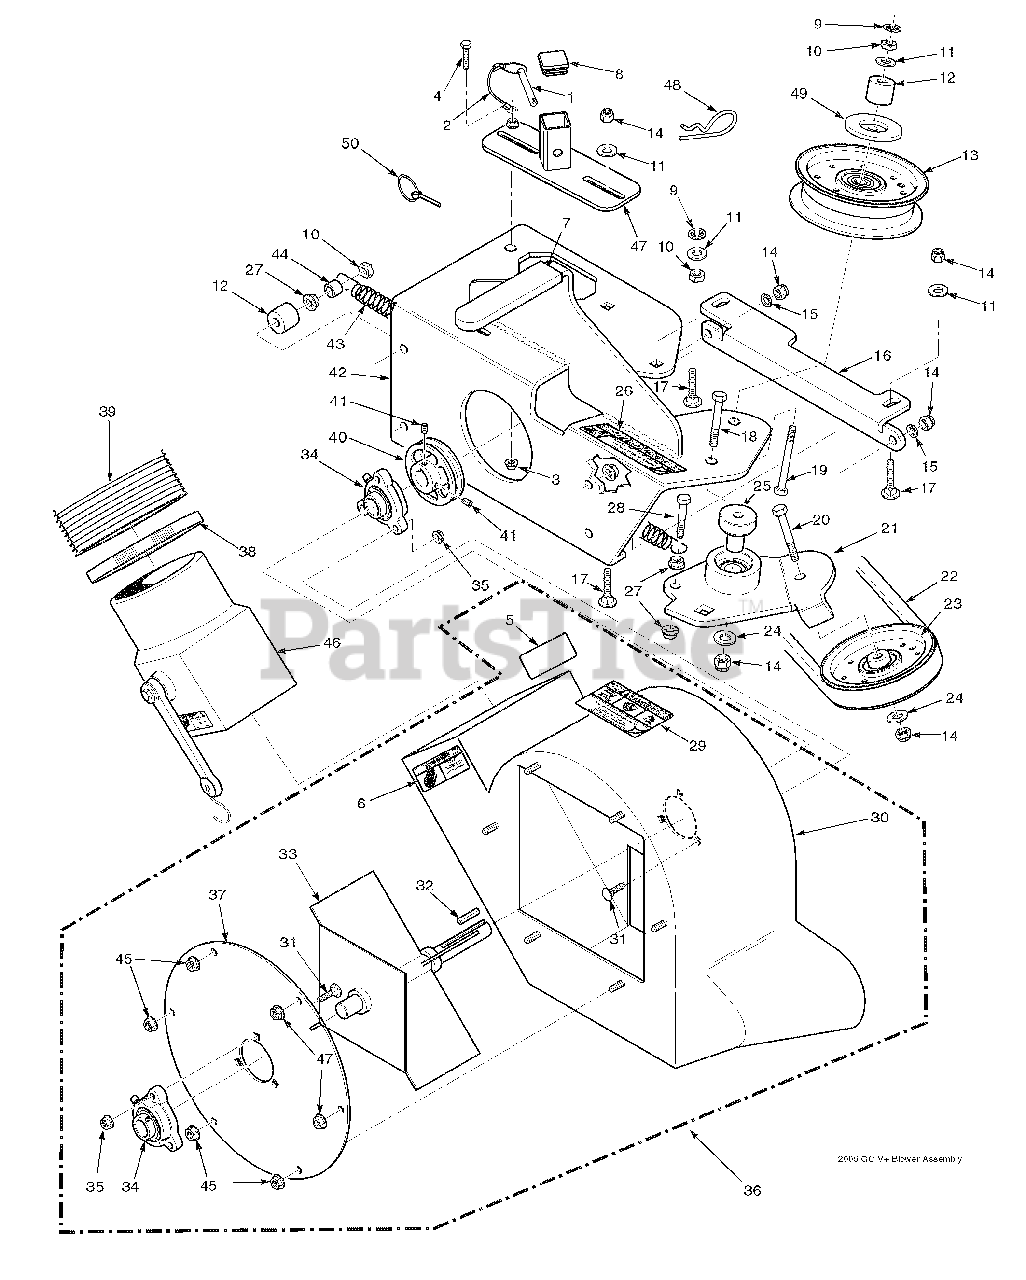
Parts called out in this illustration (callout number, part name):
1	Pin, Ring 2-1/4" Long
2	Lanyard, Deck Height Pin
3	Nut, Serr. Flange 1/4-20
4	Bolt, Hex Head 1/4-20 x 1-1/4"
5	Decal, Blower
6	Decal, Rotating Blower
7	Grip, Blower Lever
8	Cap, Square
9	Nut, Push On 3/8 Thread
10	Lock Nut, 3/8-16
11	Flatwasher, 3/8-.391 x .938 x .105
12	Spacer
13	Pulley, Idler 4" Dia. - 61"
14	Nut, Elastic Stop 3/8-16
15	Lockwasher, 3/8-16
16	Plate, Catcher Mounting
17	Bolt, Carr. 3/8-16 x 1-1/2"
19	Bolt, Hex Head 3/8-16 x 3-1/2"
20	Bolt, Hex Head 3/8-16 x 1-3/4"
21	Idler Arm Assembly - 61"
22	Belt, GC-STT-61V
23	Pulley, 3-1/2" O.D., GC-STC
24	Washer, 3/8 Hardened
25	Pivot, Idler - 61"
26	Decal, Belt Cover
27	Nut, Serr. Flange 3/8-16
28	Bolt, Hex Head 3/8-16 x 1-1/2 Gr. 8
29	Decal, Danger
30	Blower Housing Weldment w/Decals
31	Bolt, Carr. 5/16-18 x 3/4" Gr. 5
32	Key, 1/4 x 1/4 x 1-1/2"
33	Fan Weldment
34	Bearing Assembly
35	Nut, Elastic Stop 5/16-18
36	Blower Housing Assembly, GC-STT
37	Cover, Blower Housing
38	Clamp, 8-5/8" Max Dia.
39	Hose, 8.00" Dia. x 60.50" Long
40	Pulley, 4-3/4" O.D. - 1" Bore
41	Set Screw, 5/16-18 x 3/8"
42	Frame, Blower Mount
43	Spring, Main Drive
44	Spacer
45	Nut, Serr. Flange 5/16-18
46	Adapter w/Strap
47	Receiver Weldment, Mount Post - 61"
48	Hair Pin Cotter, .177 x 3-1/4"
49	Dust Shield
50	Quick Pin, 5/16" Dia.
